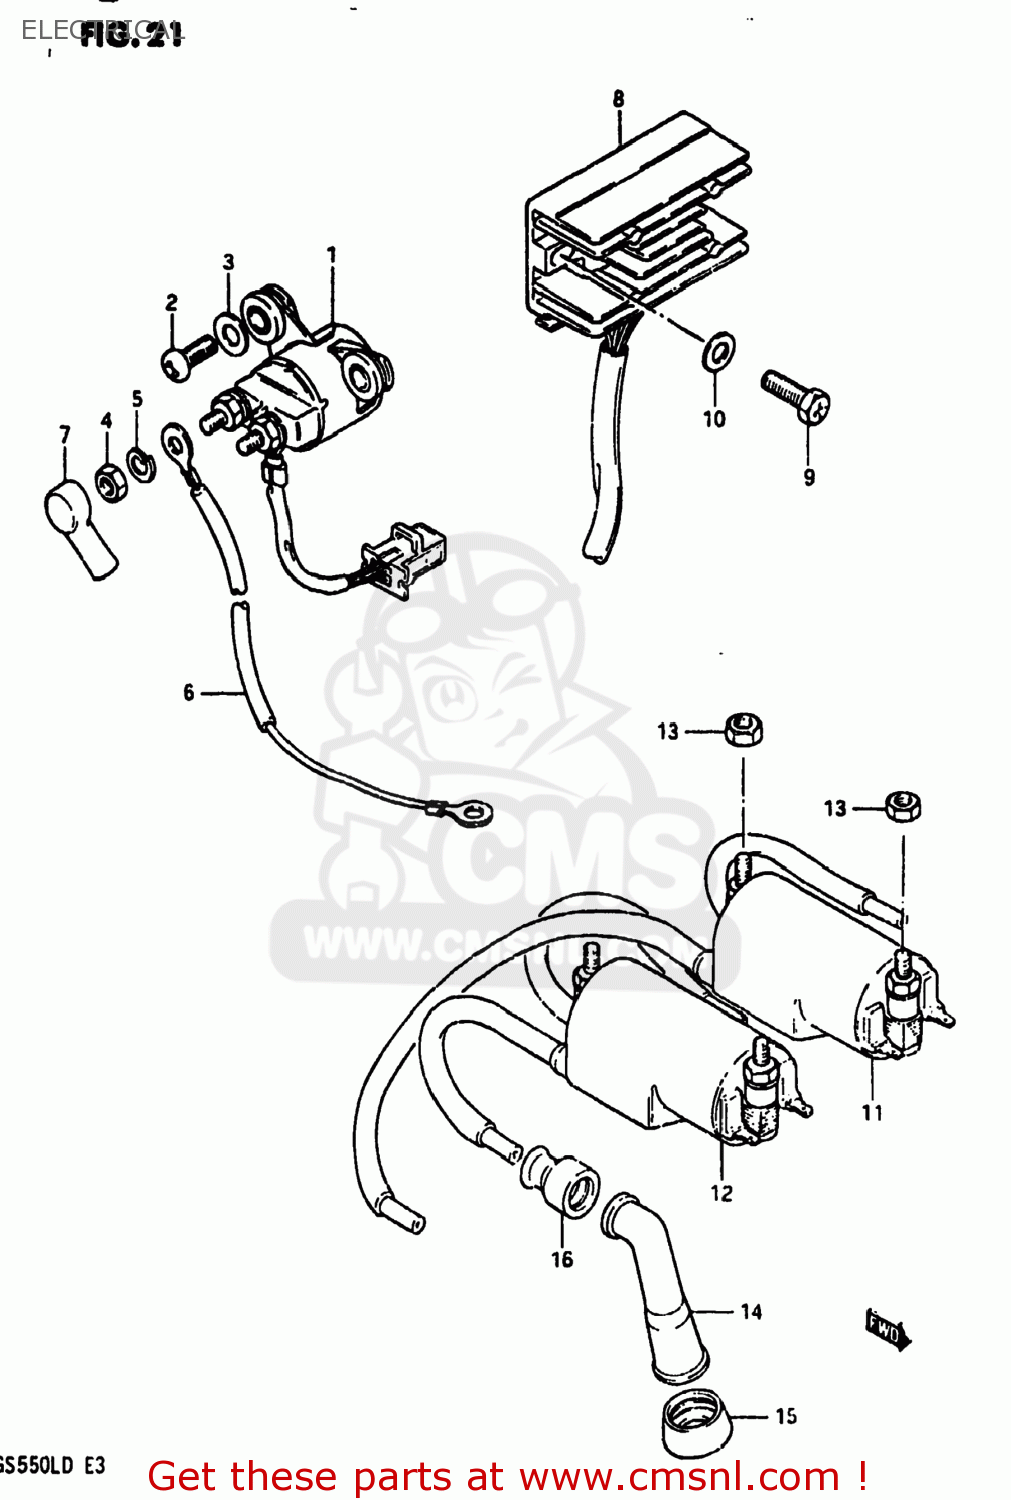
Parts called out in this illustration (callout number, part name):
1	RELAY,STARTER SWITCH
2	SCREW
3	WASHER
4	NUT 6MM
5	LOCK WASHER
6	WIRE,STARTER MOTOR LEAD
7	CAP,STARTER MOTOR TERMINAL
8	RECTIFIER ASSEMBLY
9	BOLT(6X20)
10	WASHER
11	COIL ASSEMBLY,IGNITION
12	COIL ASSEMBLY,IGNITION
13	NUT
14	CAP ASSY,SPARK PLUG
15	SEAL,SPARK PLUG
16	SEAL,SPARK PLU
